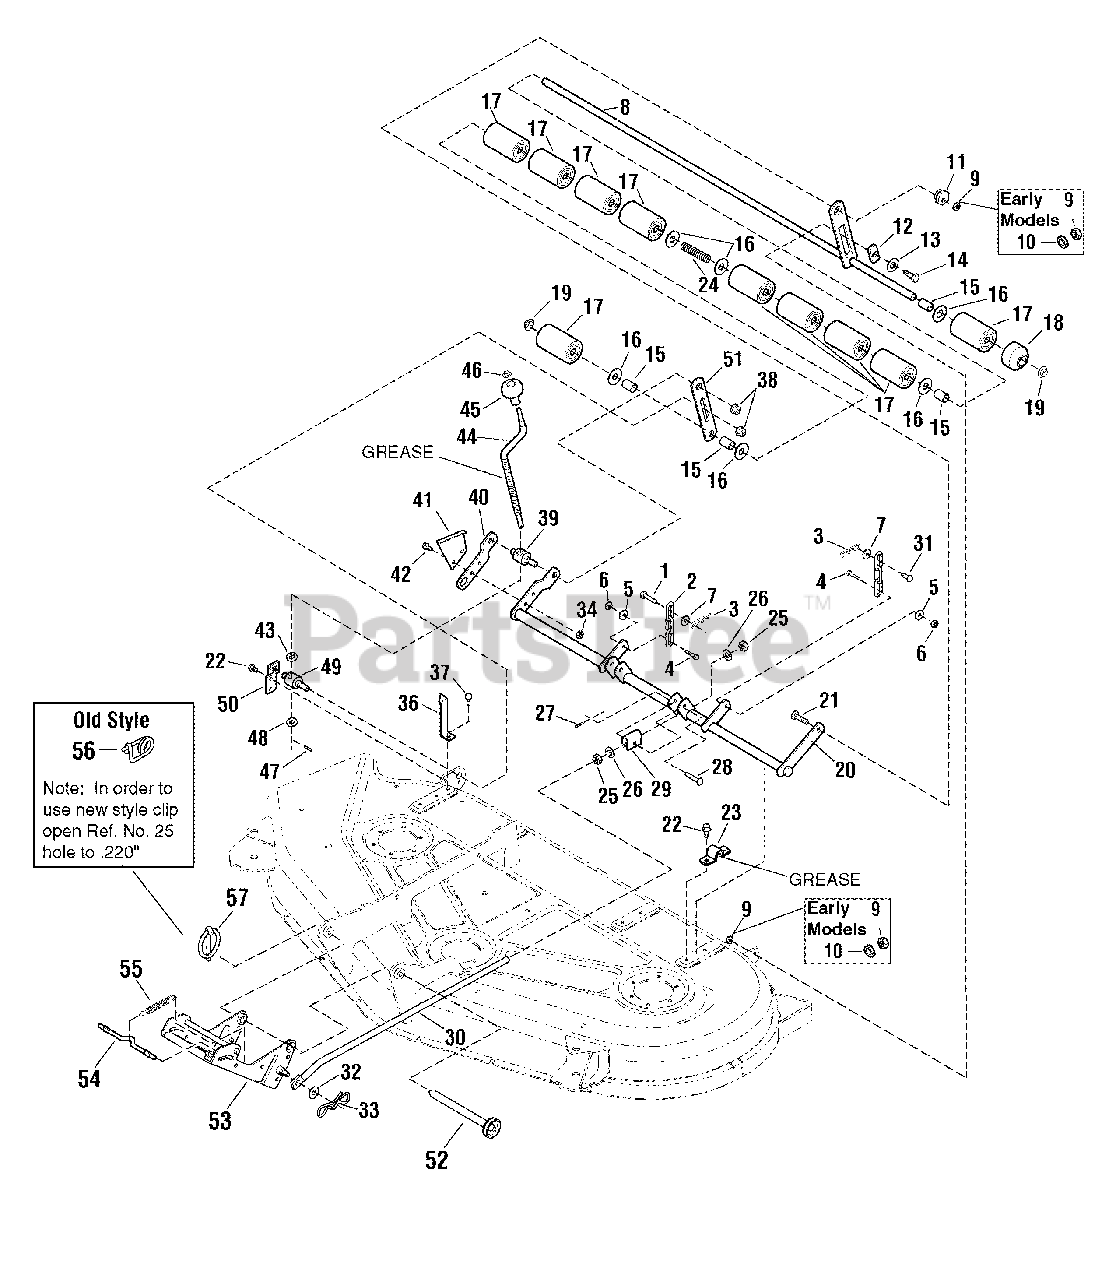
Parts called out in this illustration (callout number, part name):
1	ASSEMBLY, Pin & Cup
2	CHAIN, 3 Links
3	CLIP, Hair Pin
4	CAPSCREW, Hex Head, 5/16-18 x 1-1/2, G 8
5	WASHER, 5/16
6	LOCKNUT, Hex, 5/16
7	WASHER, 3/8
8	ASSEMBLY, Roller Bar
9	NUT, Hex Alum Insert Lock, 3/8-16 (Later Models)
9	NUT, Hex, 3/8-16 (Early Models)
10	WASHER, Lock, 3/8 (Early Models)
11	NUT, Hex Adjusting, .99 DIA .687
13	WASHER, 1/2
14	BOLT, Shoulder, 3/8-16 X 1.34
16	WASHER, 5/8
17	ROLLER, Full
18	ROLLER, Half
19	PUSHNUT, 5/8
20	ASSEMBLY, Rocker Shaft
21	CARRIAGE BOLT, 3/8-16 x 1-1/2, G 5
22	CAPSCREW, Hex Head, Taptite, 5/16-18 x 3/4
23	STRAP
25	NUT, Hex, 5/8-11
26	WASHER, 5/8
27	PIN, Clip Hair .093 Diameter
28	PIN, Round Head, 3/8 x 2
29	TRUNNION
31	PIN, 3/8 x 1
32	WASHER, 1/2
33	PIN, Bow Tie
34	NUT, Hex, 5/16-18
36	INDICATOR, Height of Cut
37	CAPSCREW, Hex Head, Taptite, 5/16-18 x 1 1/4
38	NUT, Hex Flange, 1/2-13
41	BRACKET, Height of Cut
42	CAPSCREW, Hex Head, 5/16-18 x 1-1/4, G 5
43	WASHER, 1/2
44	CRANK, Height Adjust
45	KNOB, Spinner
46	PUSHNUT, 3/8
48	WASHER, Detent, 1/2
50	SUPPORT, Trunnion
53	ASSEMBLY, Hitch
56	PIN, Safety (Early Models)
